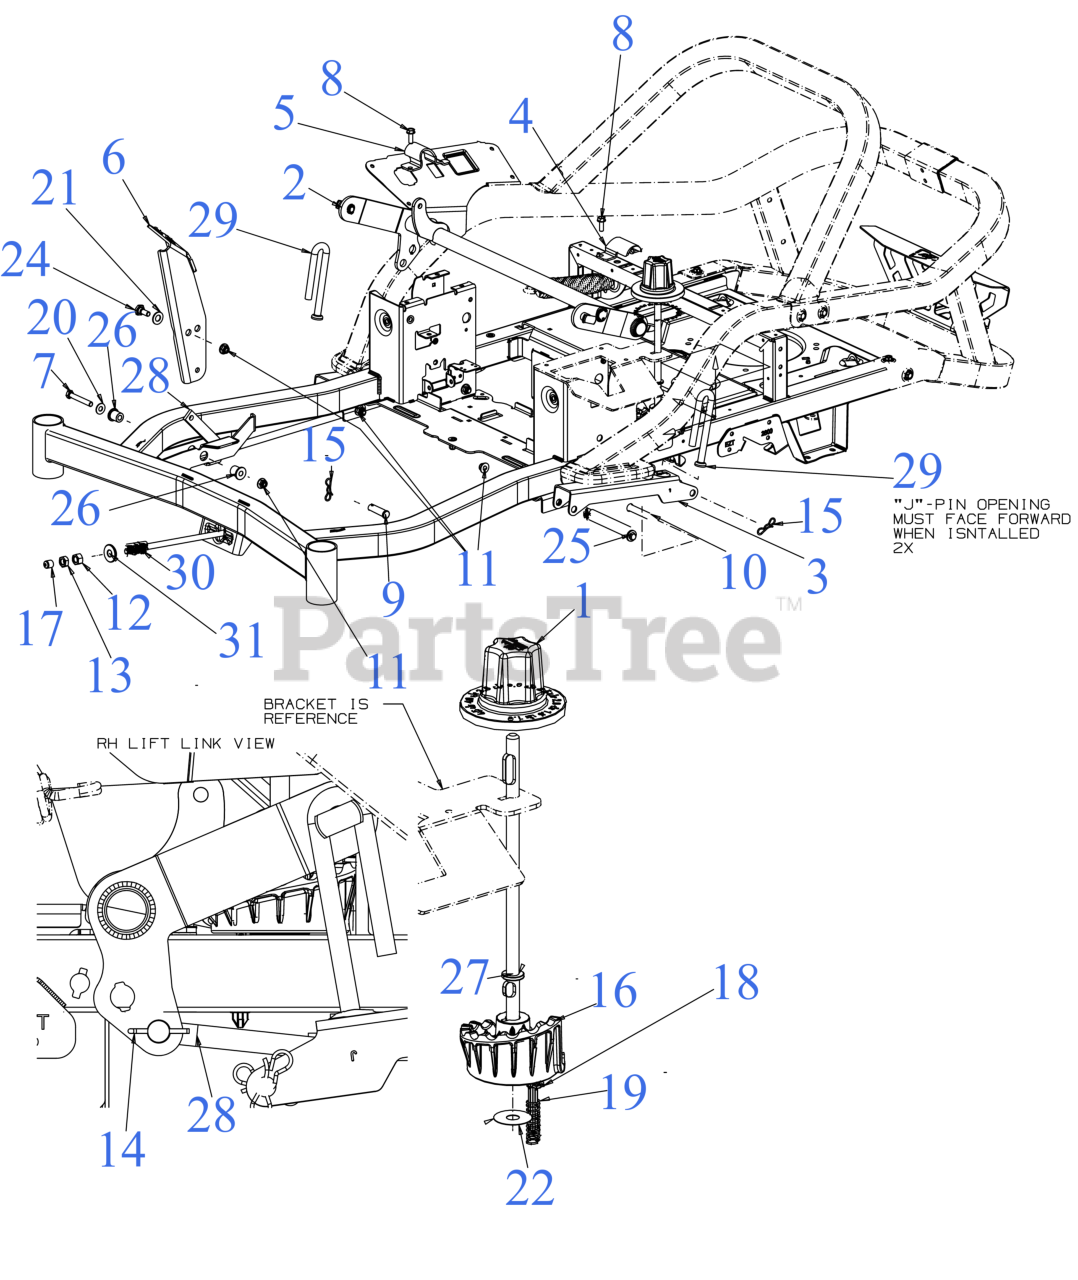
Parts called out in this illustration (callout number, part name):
1	DECK HEIGHT ADJUSTMENT KNOB
2	LIFT SHAFT ASSEMBLY
3	DECK LIFT LINK
4	LIFT SHAFT (RETAINER) (LH)
5	LIFT SHAFT (RETAINER) (RH)
6	DECK LIFT PEDAL
7	HEX SCREW-3/8-16X2.5 GR5
8	SCREW 5/16-18 x .875 GR5
8	SCREW 5/16-18 x 1.25
9	CLEVIS PIN .500 x 1.875
10	CLEVIS PIN .50 x 2.5
12	HEX NUT NYLOK 1/2-13
14	COTTER PIN
15	BOW TIE COTTER PIN
16	DECK LIFT CUP
17	LIFT ROD END CAP
18	DETENT PLUNGER
19	COMPRESSION SPRING .531 OD 1.75 LG
20	FLAT WASHER
21	FLAT WASHER .510 x .995
22	SHIM WASHER .50 x 1.5 x .02
24	SHOULDER SCREW
25	SHLDER SCREW .498x5.0 3/8-16
26	FLANGE BEARING (.38x.75x.77)
27	DECK HEIGHT ADJUSTMENT ROD
28	LIFT PEDAL ROD
29	HANGER LINK ROD
30	DECK FRONT LIFT ROD
31	DECK LIFT PIVOT CUP
